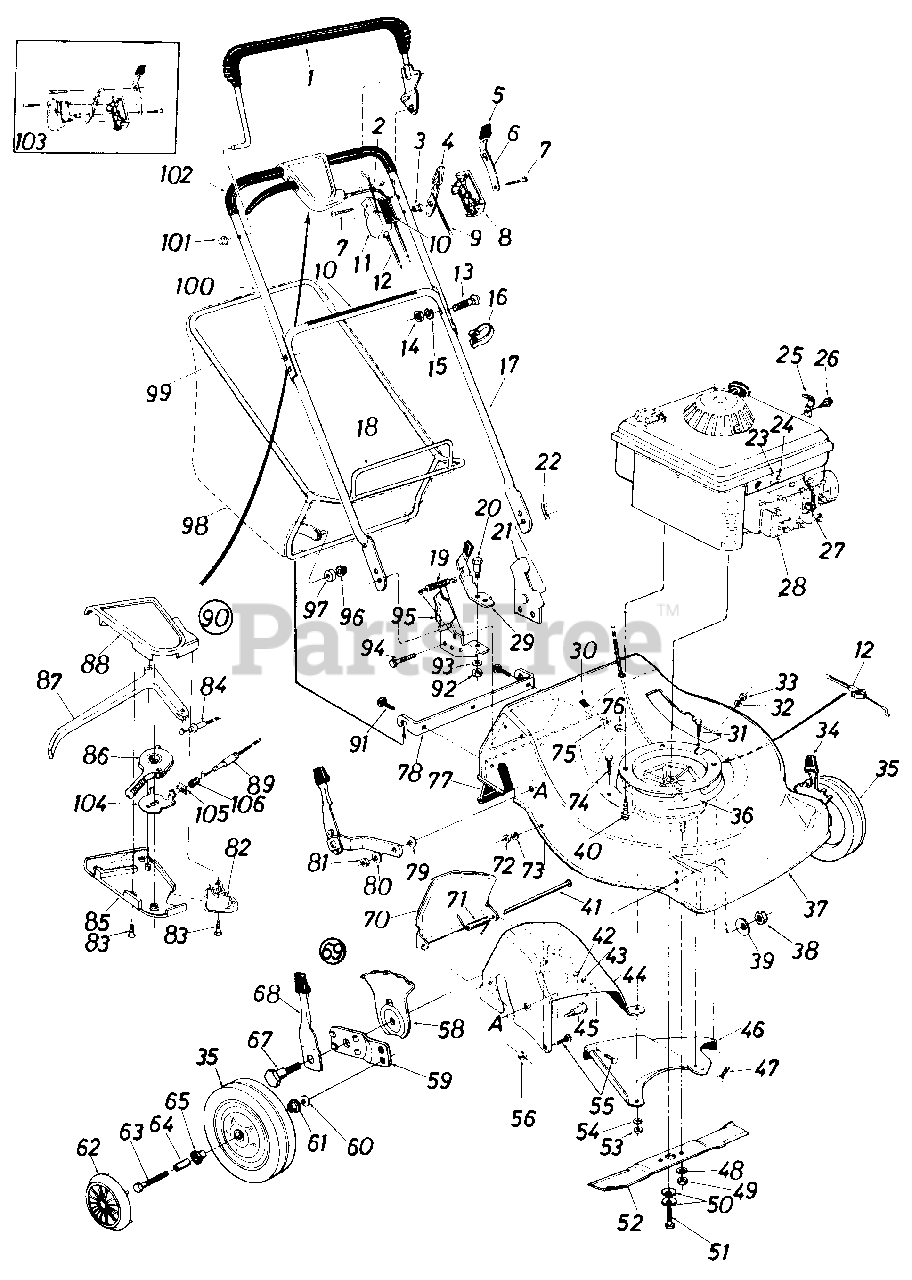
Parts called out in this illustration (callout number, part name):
1	L.H. Bail Ass'y.
3	Control Disc Pin
4	Throttle Control Lever
5	Spring Lever Knob
6	Lockout Spring
7	Truss Mach. Hi-B Tap Scr. #12 x 1.50" Lg.
8	Control Panel Half
9	Throttle Control Wire 58" Lg.
10	Control Labels
11	Clutch Panel Half
12	Clutch Cable 46" Lg. Black
13	Curve Carr. Bolt 5/16-18 x 1.38 " Lg.
14	Hex Nut 5/16-18 Thd.*
15	L-Wash. 5/16" I.D.*
17	Lower Handle (Chrome)
20	Shld. Bolt .437" Dia. x .162
21	Handle Bracket Ass'y. L. H .
22	Hairpin Cotter 5/16" Dia.
23	Hex "B"-Tap Scr. #10 x .38" Lg.
24	Casing Clamp
25	Cable Clip
26	Hex Sems Scr. #10-32 x .62" Lg.
27	Spark Plug Insulator
28	Engine
29	Grass Catcher Lock Lever w/ Knob
31	Hex TT-Tap Scr. 1/4-20 x .75" Lg.
32	L-Wash. 1/4" I.D.*
33	Hex Nut 1/4-20 Thd.*
34	Height Adj. Ass'y. L.H.
35	Front Wheel Ass'y. Comp. 8 x 1.75
36	Blade/Brake Clutch Ass'y. Comp.
39	Bel I-Wash. .39 " I.D. x 1.38" O.D.
40	Hex Wash. Hd. TT-Tap Scr. 3/8-16 x 1.0" Lg.
42	Hex Nut 1/4-20 Thd.*
43	L-Wash. 1/4" I.D.*
44	Rear Chute R.H.
45	Shld. Bolt .500" Dia. x .685"
46	Rear Baffle L.H.
47	Carr. Bolt 1/4-20 x .50" Lg.*
48	L-Wash. 3/8" I.D.*
49	Hex Nut 3/8-24 Thd. (Grade 8)
50	Bell-Wash. .40" I.D. x .88" O.D.
51	Hex Cl-Bolt 3/8-24 x 2.0" Lg. (Grade 8)
53	Hex Nut 1/4-20 Thd.*
54	L-Wash. 1/4" I.D.*
55	Carr. Bolt 1/4-20 x .50" Lg.*
56	Hex Sems Nut 1/4-20 Thd.
58	Height Adj. Plate
59	Wheel Pivot Bar
60	Bell-Wash. .40" I.D. x .88" O.D.
61	Flg. Ball Brg. 3/8" I.D.
62	Plastic Hub Cap
63	Hex Bolt 3/8-16 x 1.75" Lg.
64	Spacer.375" I.D. x .505" O.D.
65	Flg. Ball Brg. 1/2" I.D.
67	Shld. Bolt .50" Dia. x .430
68	Spring Lever Ass'y. w/ Knob
69	Height Adj. Ass'y. R.H.
70	Chute Door
71	Torsion Spring
72	Hex Nut 1/4-20 Thd.*
73	L-Wash. 1/4" I.D.*
74	Hex Bolt 1/4-20 x .88" Lg.
75	Fl-Wash. .285" I.D. x 1.25" O.D.
76	Hex Sems Nut 1/4-20 Thd.
78	Grass Catcher Hitch Brkt.
79	Bell-Wash. .400" I.D. x 1.13" O.D.
80	Bell-Wash. .400" I.D. x .88" O.D.
81	Hex Jam Nut 3/8-16 Thd.
82	Cable Mounting Cap
83	Flat "C"-Sunk Hd. Tap Scr. #10 x .75" Lg.
84	S.P. Cable x 53" Lg.
85	3-Sp. S.P. Control Lower Cover
86	Shimano 3-Sp. Shift Lever
87	Control Lever
88	3-Sp. S.P. Control Upper Cover
89	Shimano 3-Sp. Solid Shift Cable
90	Clutch Control Housing Comp.
91	Carr. Bolt 1/4-20 x .75" Lg.*
92	Hex Nut 5/16-18 Thd.*
93	L-Wash. 5/16" I.D.*
94	Hex L-Wash. Hd. AB-Tap Scr. 1/4" x .62" Lg.
95	Handle Bracket Ass'y. R.H .
96	Push Nut 3/8" Rod
97	Plastic Roller
98	Grass Bag (Without Flip Top)
99	Catcher Upper Frame
100	Upper Handle (Chrome)
101	Cap Speed Nut
102	Grip
103	Control Housing Comp.
104	Shimano 3-Sp. Shift Lever Brkt.
105	Shimano 3-Sp. Cable Spring Brkt.
106	Shimano 3-Sp. Cable Mounting Spring
